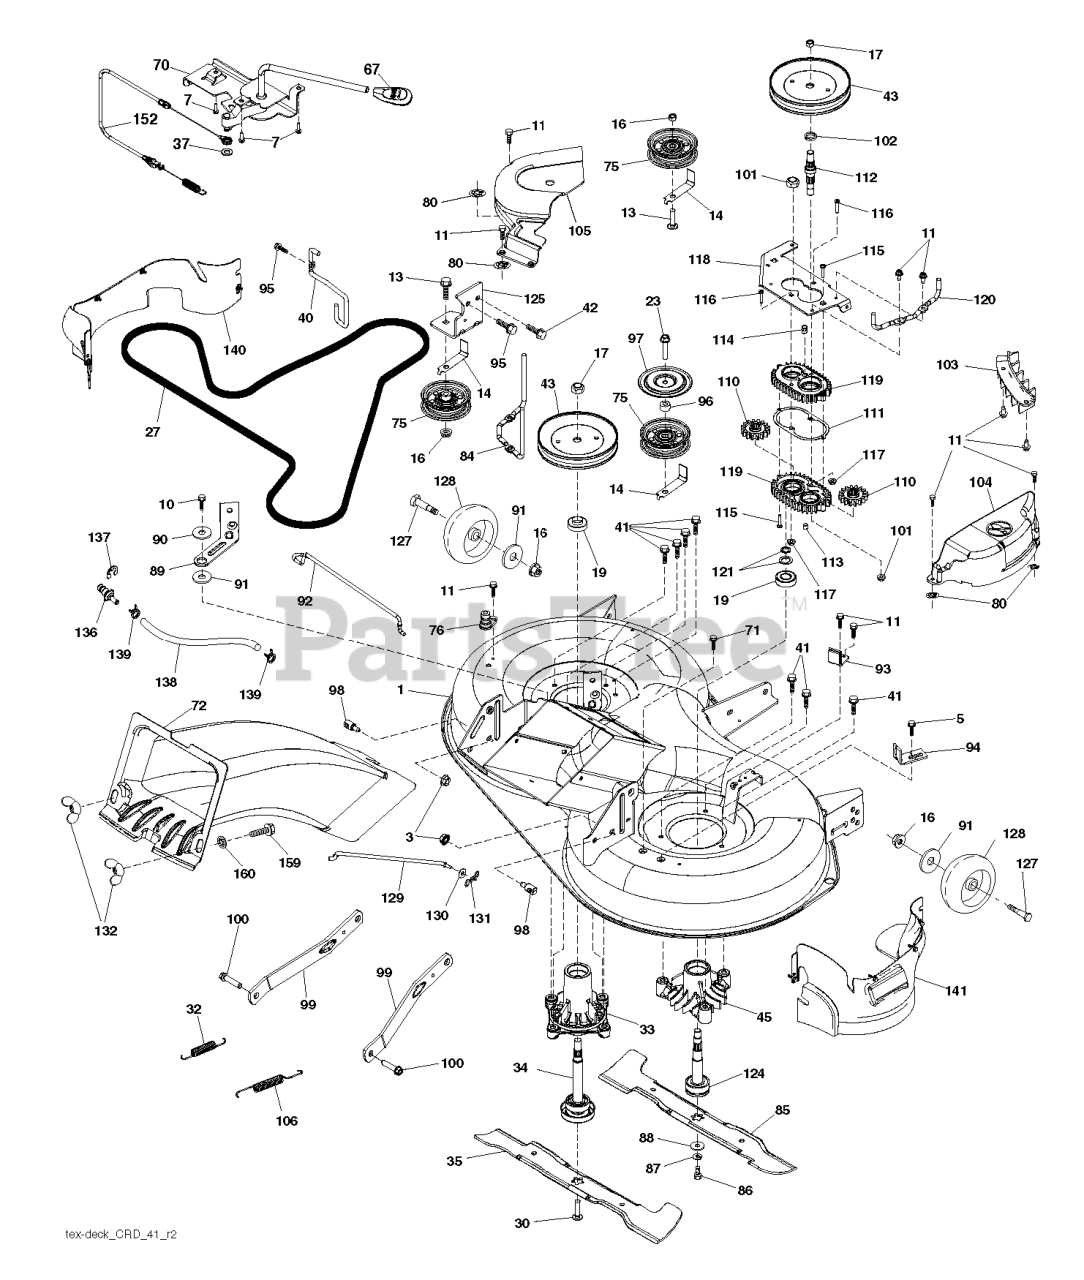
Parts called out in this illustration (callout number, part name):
1	DECK.WELDMENT.97.TEX.498
3	NUT LOCK HEX FLANGE 5/16-18
5	BOLT.5/16HEX.WHS.HD
7	SCREW.#10 X 0.750.BOS
10	SCREW 3/8-16X1
11	SCREW.1/4-20X5/8
13	BOLT.3/8-16X1.50
14	KEEPER, BELT IDLER
16	NUT LOCK FLG 3/8-16 UNC
17	NUT.FLANGE.LOCK.TOP
18	WASHER.SPACER.MANDREL
23	SCREW LT
27	BELT V-BELT DRIVE
30	BOLT.WASHER.ASM.7/16-2
32	SPRING RETURN
33	RP.HOUSING.MANDREL.4PT.
34	SHAFT.ASM.MDRL.N/GREASE.38
35	BLADE.3N1.LH.CRD.97
37	WASHER
40	KEEPER BELT ENGINE LH
41	BOLT.HEX.WASHR.HED.313-18X1.19
42	SCREW
43	PULLEY.MANDREL.5.438.PD
45	HOUSING.MANDREL.44/46" VENT
67	HANDLE.CLUTCH.CABLE.LT
70	CLUTCH.ASM.MANUAL.LT.PRED
71	SCREW 3/8-16X1/2
72	CHUTE REAR CRD UPPER CHUTE TEX
75	FLAT IDLER PULLEY
76	1/2" BARB.DECK.WASHOUT.PORT
80	PALNUT 1/4
84	KEEPER.BELT.MANDREL.PULLEY
85	BLADE.3N1.RH.CRD.97
86	BOLT.3/8-24X1.25GR8. LHTHRD
87	LOCKWASHER
88	WASHER.BLADE
89	ARM.BRAKE.97.LH
90	SPACER.RETAINER
91	WASHER
92	ROD ROD BRAKE
93	ARM.BRAKE.97.RH
94	BRKT.CLUTCH.CABLE
95	SCREW, 3/8-16X3/4
96	SPACER
97	PROTECTOR
98	STUD.FASTNER.W/ANTI-ROTATE
99	ARM.SUSPENSION.MOWER.R
100	BOLT.SHOULDER
101	NUT.CROWNLOCK.9/16 -18.UNC
102	SPACER BEARING
103	GUARD GUARD FRONT VENT
104	97.CRD.RH.MANDREL.COVER
105	MANDREL MANDREL COVER LH
106	SPRING.BRAKE.RETURN.38"
110	CRD.SPUR.GEAR
111	GASKET GASKET GEARCASE
112	SHAFT SHAFT. CRD GEARCASE ADAP
113	PLUG PLUG OIL
114	VENT.BREATHER.1/8 NPT
115	SCREW
116	BOLT.CARIGE.SS.1/4-20X1.75GR5
117	NUT T
118	ARM ARM CLUTCHING
119	GEARCASE GEARCASE SUBASM
120	BRACKET KEEPER BELT RH
121	WASHER WASHER
124	MANDREL SHAFT NON/GREASE
125	BRACKET
127	BOLT.SHOULDER.3/8-16X3-5/8.
128	RP WHEEL. GUAGE RALLY
129	ROD.ANTI.SWAY.48/54"K4
130	WASHER
131	PIN.COTTER.5/16.BOW TI
132	KNOB.HANDLE.3/8.TRI-POINT.BLAC
136	PLUG WASHOUT PORT HOOKUP
138	HOSE.3/8ID.BULK.12"
139	HOSE.3/8.CLAMP (2 2)
140	GUARD
141	GUARD SUBASM.TEX CRD 97CM RH F
152	CABLE CABLE CLUTCH MANUAL W/S
159	BOLT
